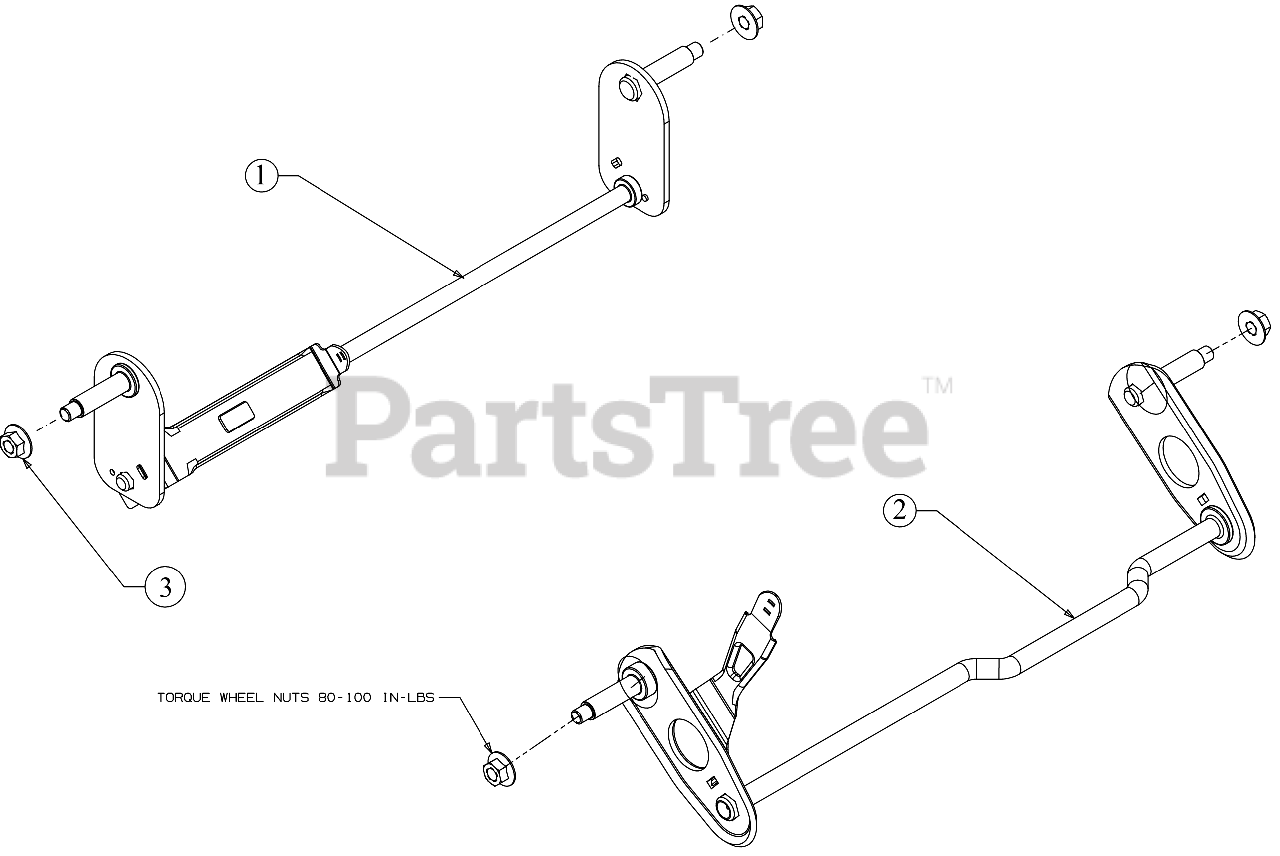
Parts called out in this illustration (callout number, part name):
1	REAR AXLE ASSEMBLY
2	8" FRONT AXLE ASSEMBLY
3	FLANGE LOCK NUT
